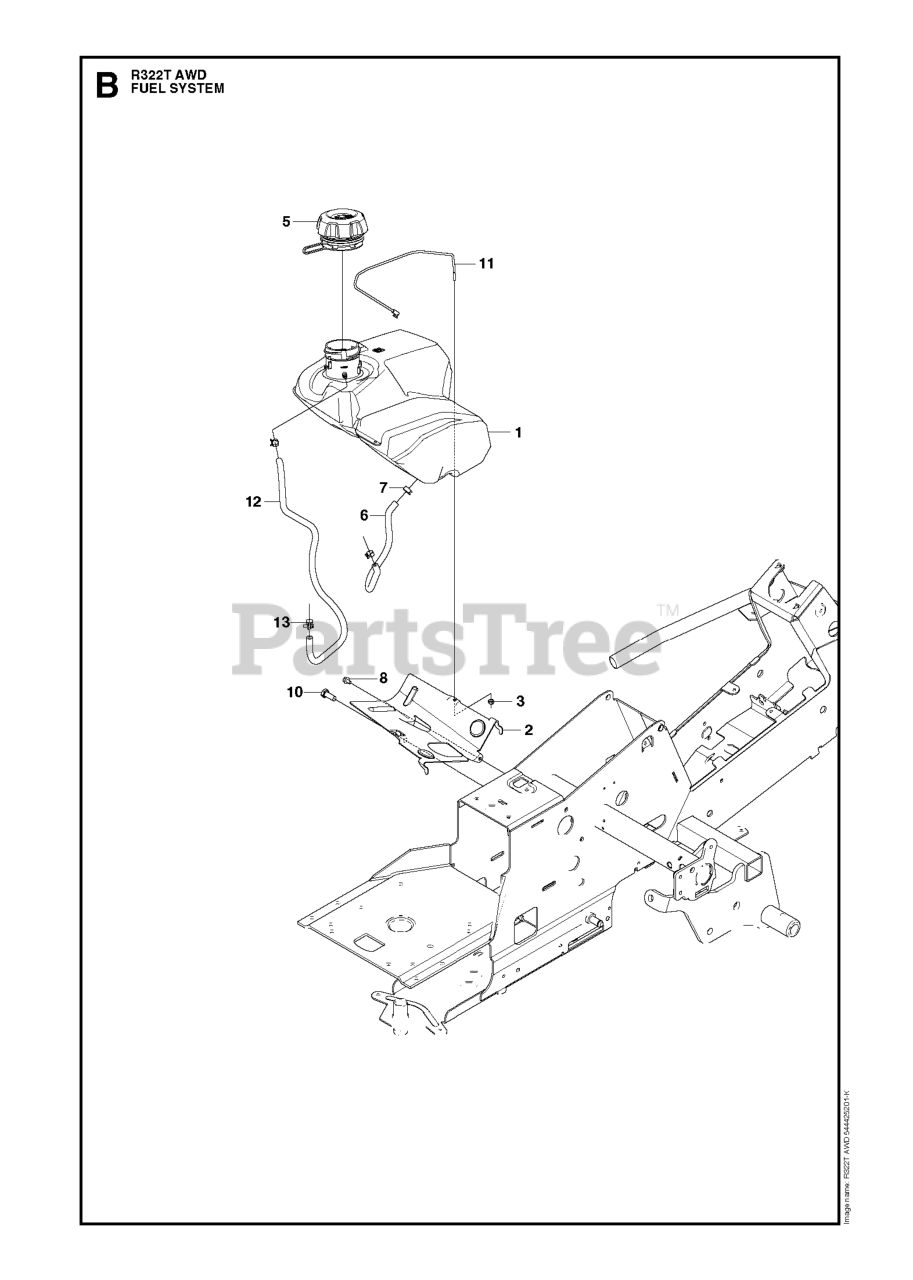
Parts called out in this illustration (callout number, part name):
3	LOCKNUT M6
5	CAP.ASM.FL.RITCH.3"E10.SYM.498
10	Screw M10x25
13	HOSE CLAMP
